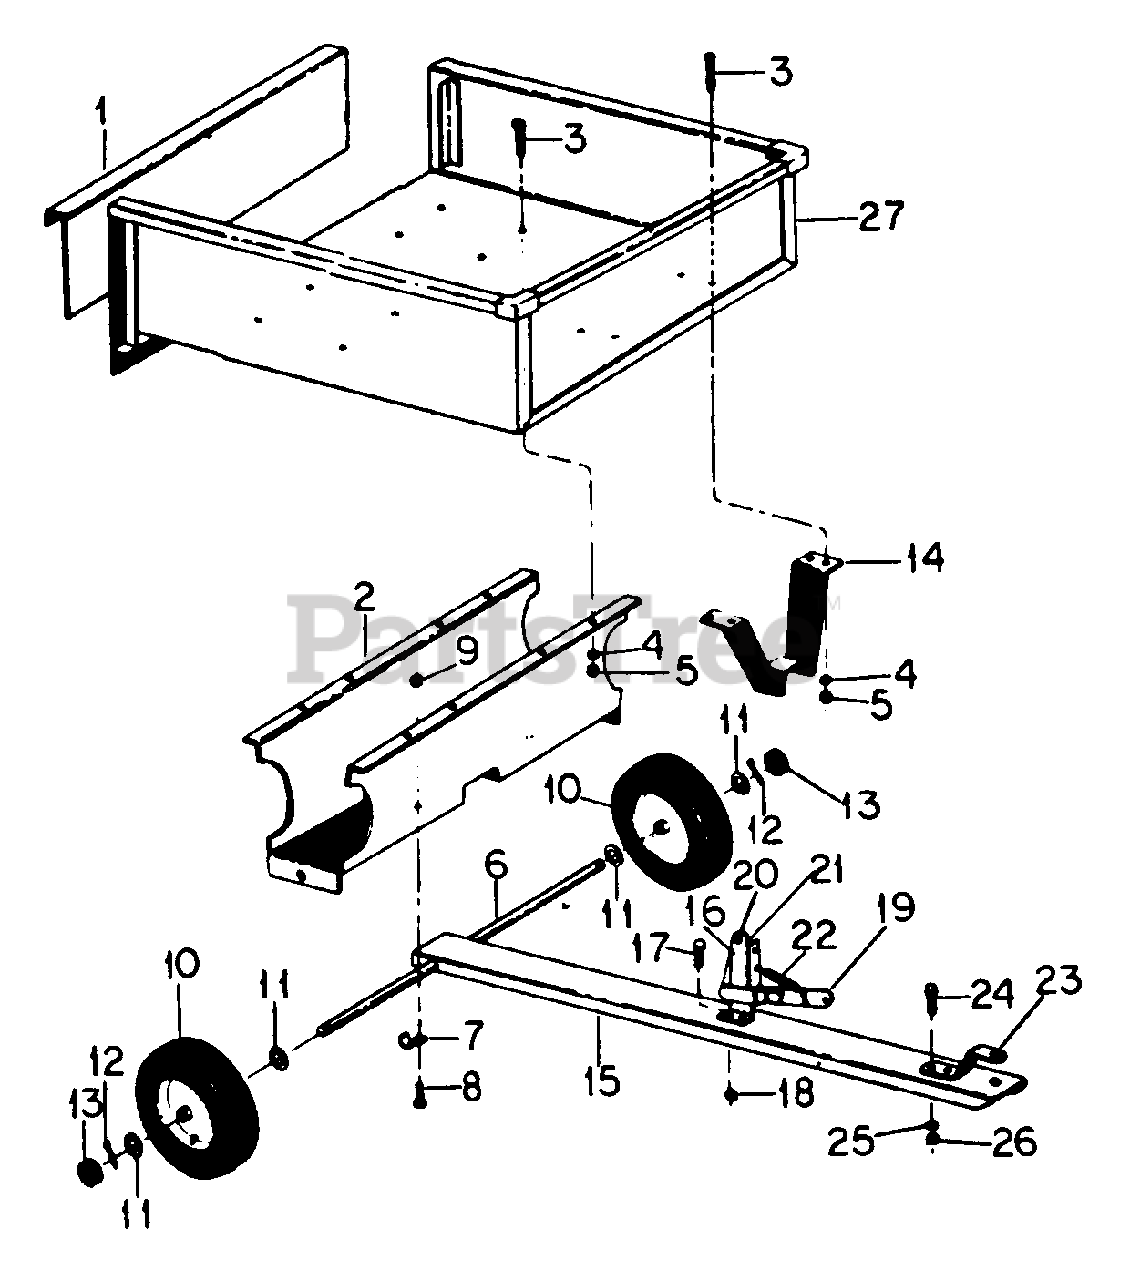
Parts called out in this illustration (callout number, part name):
1	GATE, TAIL
2	SUPPORT, WHEEL
3	SCREW, 1/4 X 1/2 ZNP P/HDS MACH
4	WASHER, 1/4 LOCK
5	NUT, 1/4 TYPE 5
6	AXLE, WHEEL
7	CLAMP, AXLE
8	BOLT, 1/4 X 1/2 TYPE 5
9	NUT, 1/4 CAD P/T LOCK TYPE 5
10	WHEEL ASSY W/TIRE
11	WASHER, 1.031 X 1.62 X .06 ZND
12	PIN, 1/8 X 1-1/4 PLN COT
14	BRACKET, LATCH STAND
16	BRACKET, LATCH LOCK
17	BOLT, 1/4 X 1/2 TYPE 5
18	NUT, 1/4 CAD P/T LOCK TYPE 5
19	BRACKET ASSY, LOCK
20	BOLT, 1/4 X 3/4 TYPE 5
21	NUT, 1/4 CAD P/T LOCK TYPE 5
22	SPRING, EXTENSION
23	BRACKET, HITCH
24	BOLT, 3/8 X 1 TYPE 5
25	WASHER, 3/8 LOCK
26	NUT, 3/8 TYPE 5
27	$BODY
